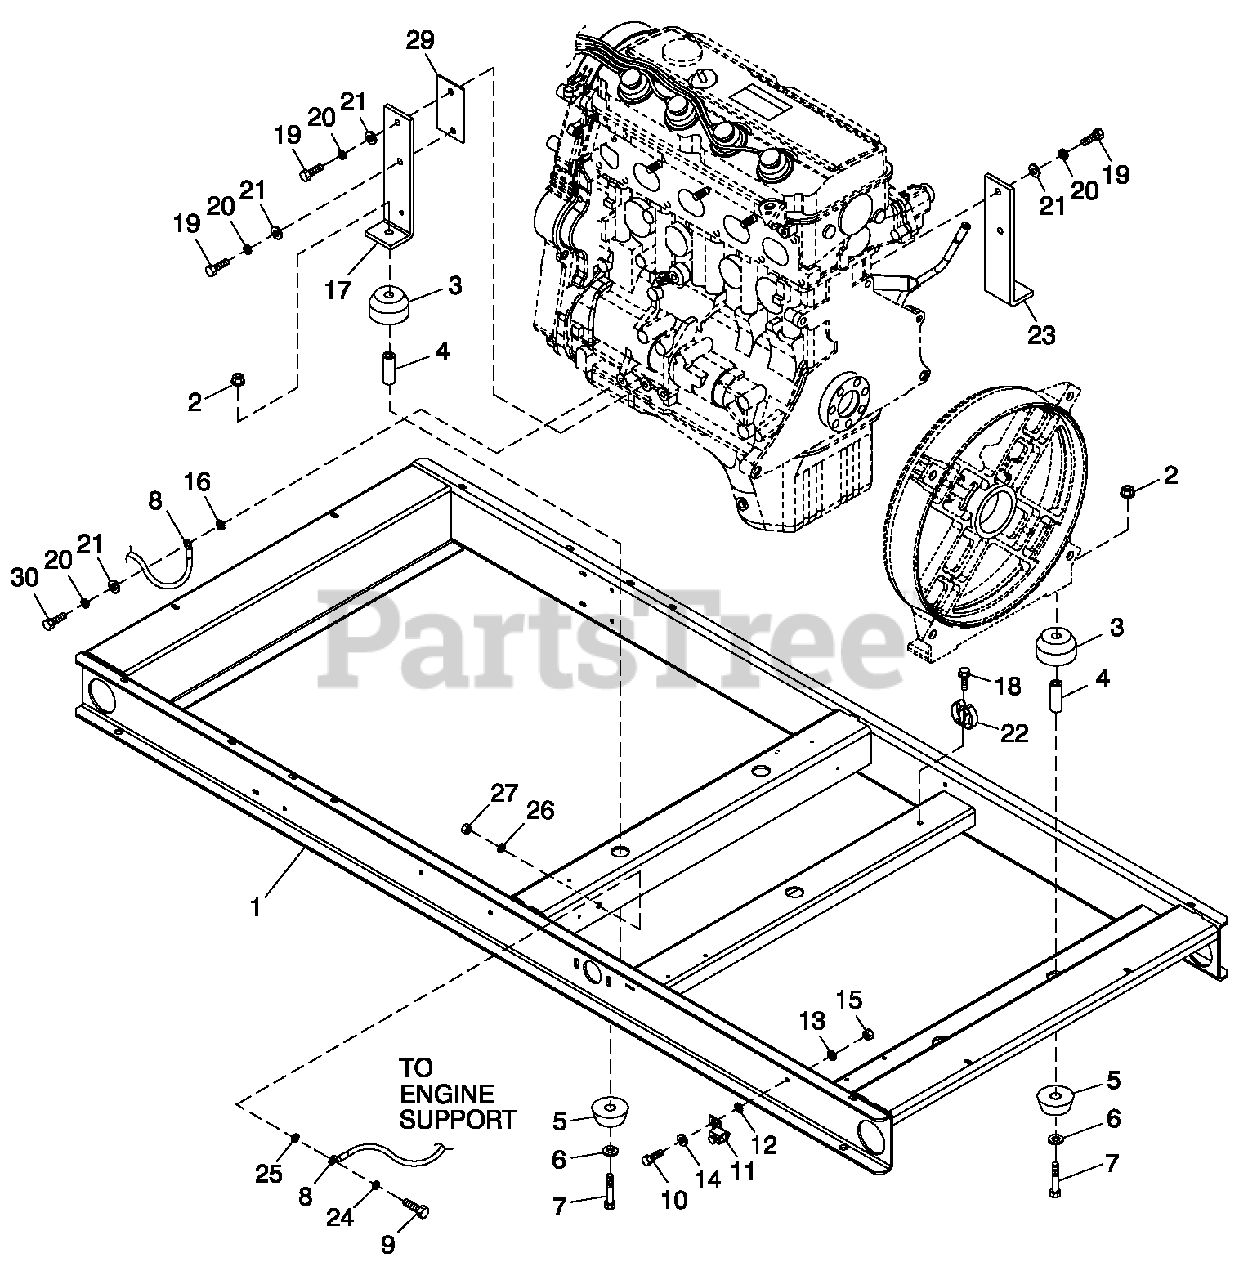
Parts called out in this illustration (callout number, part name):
1	WELDMENT FRAME 2.4L C2
2	NUT FLANGED HEX M12-1.75
3	DAMPENER VI BRATION 40 BLUE
4	SPACER .49 X .62 X 1.87 PWDR/ZNC
5	DAMPENER VIBRATION
6	WASHER FLAT M12
7	SCREW HHC M12-1.75 X 80 G8.8
8	ASSY WIRE 14.00"
9	SCREW HHC M8-1.25 X 30 G8.8
10	SCREW HHC M6-1.0 X 16 G8.8
11	LUG SLDLSS #2-#8 X 17/64 CU
12	WASHER SHAKEPROOFINT 1/4
13	WASHER LOCK M6-1/4
14	WASHER FLAT M6-1/4 ZINC
15	NUT HEX M6 -1.0 G8 YEL CHR
16	WASHER SHAKEPROOF INT 3/8
17	SUPPORT LH ENGINE 2.4L
18	SCREW HHTT M4-0.7 X 8 BP
19	SCREW HHC M10-1.25 X 30 G8.8
20	WASHER LOCK 7/16
21	WASHER FLAT 3/8-M10 ZINC
22	SPRING CLIP HOLDER .37-.62
23	SUPPORT RH ENGINE 2.4L
24	WASHER LOCK M8-5/16
25	WASHER SHAKEPROOF INT 5/16
26	WASHER FLAT 5/16-M8 ZINC
27	NUT HEX M8-1.25 G8 CLEAR ZINC
29	SPACER ENGINE MOUNT (2.4L G1)
30	SCREW HHC M10-1.25 X 25 C8.8
